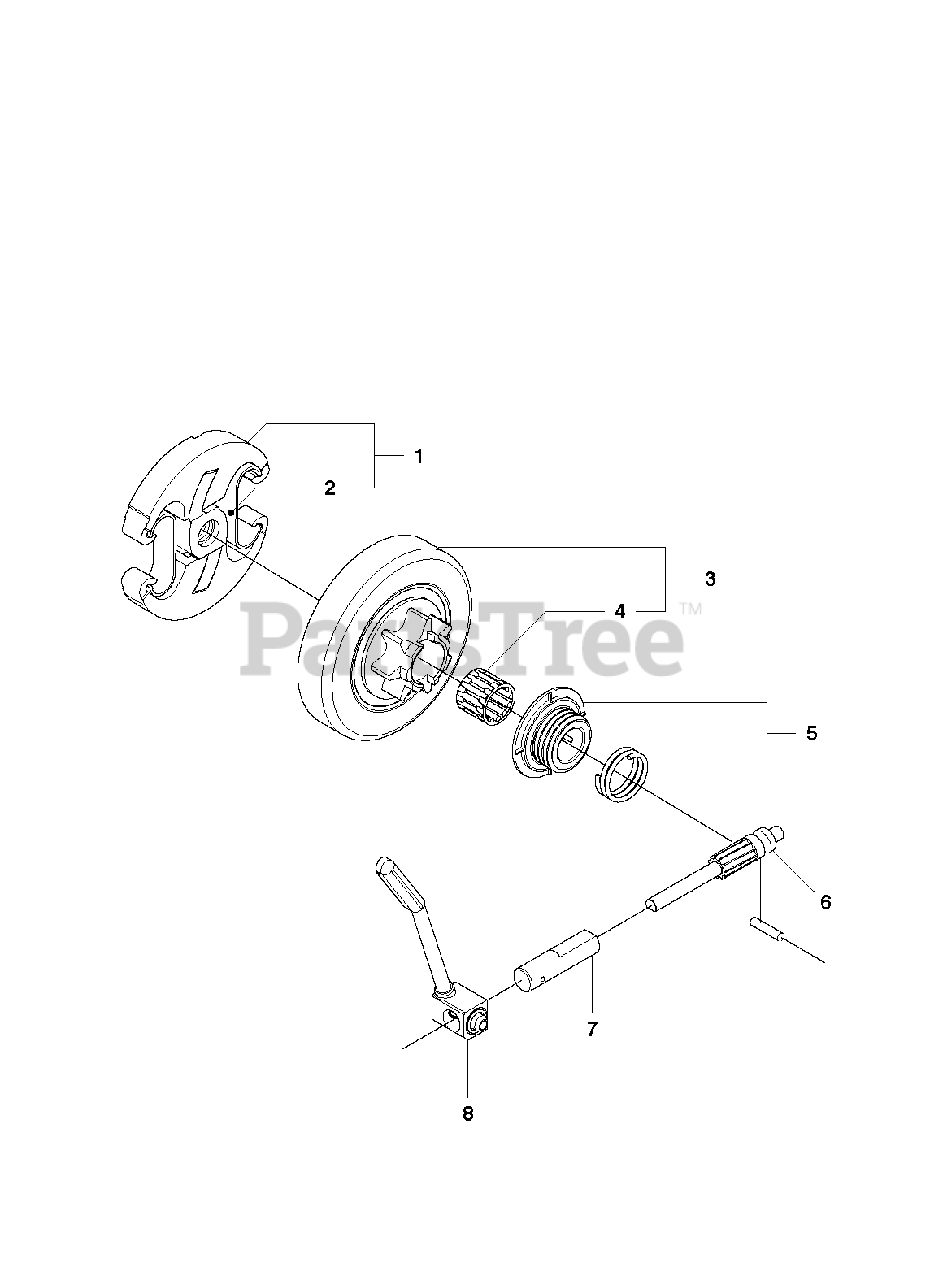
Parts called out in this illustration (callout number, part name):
2	SPRING
3	CLUTCH DRUM
4	NEEDLE BEARING
6	PISTON PUMP
7	PUMP CYLINDER
8	OIL HOSE
